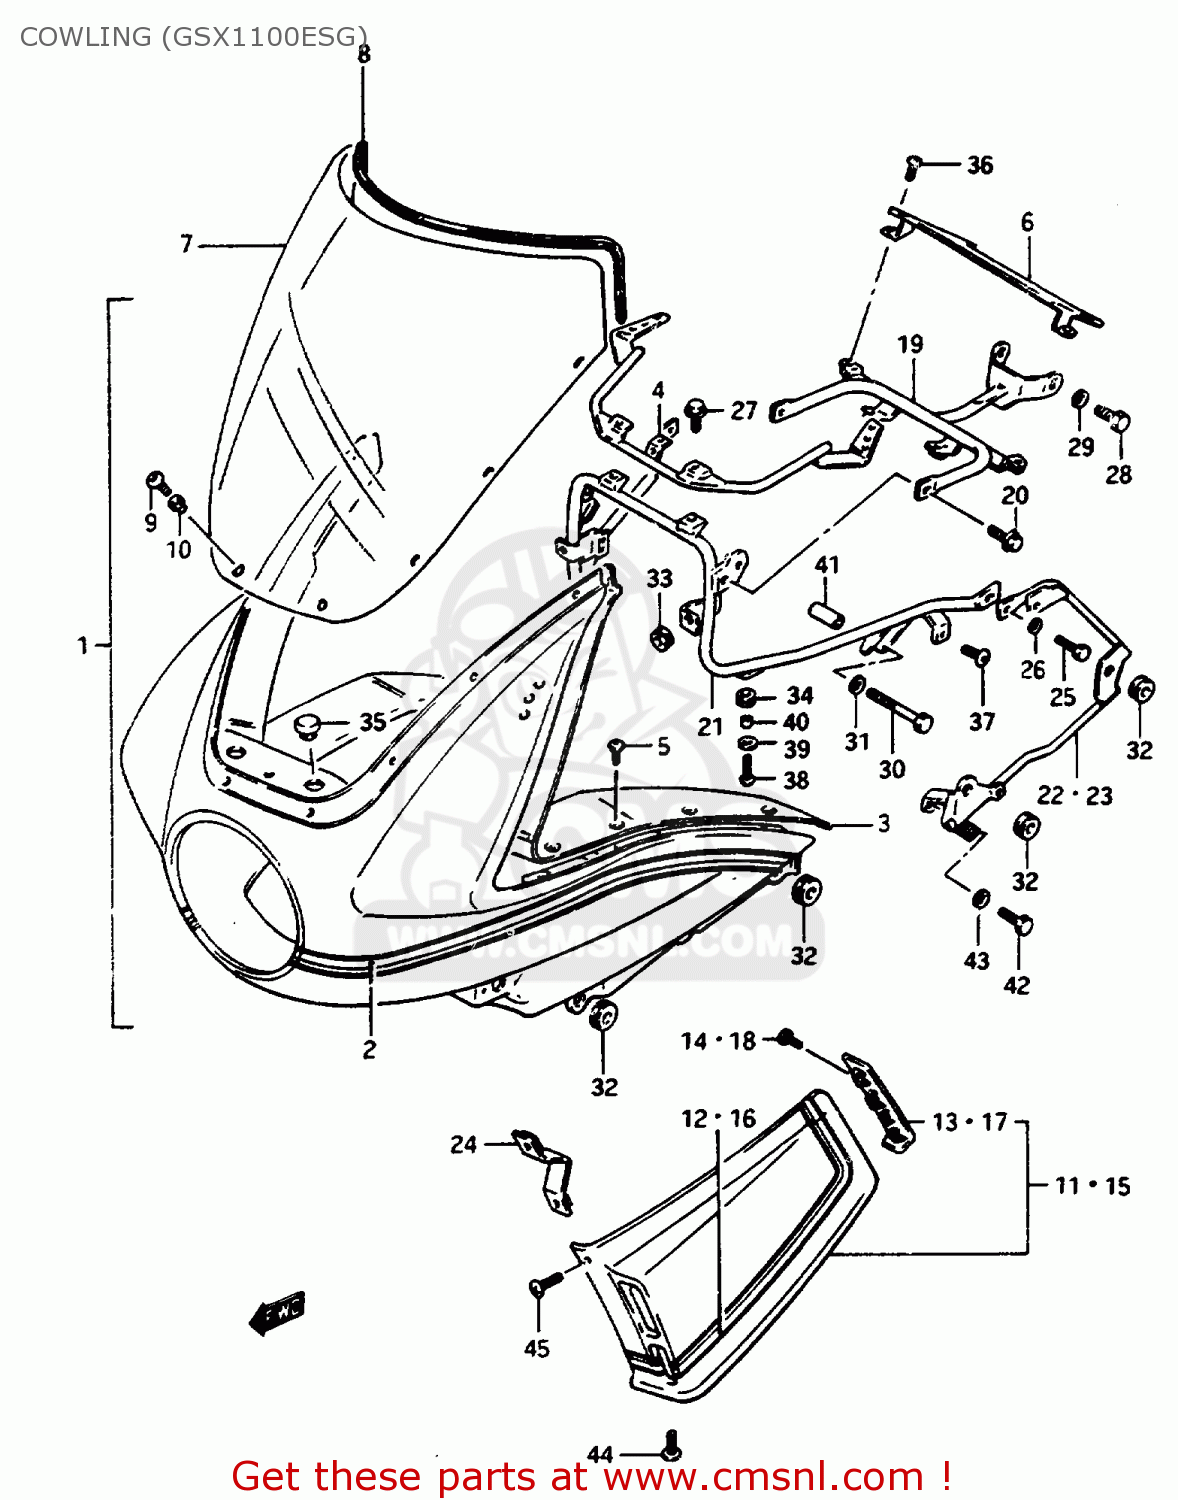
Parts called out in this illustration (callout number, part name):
1	COWLING ASSY (WHITE/RED)
2	TAPE SET,COWLING
3	PANEL,COWLING
4	BRACE,COWLING BODY
5	SCREW, PANEL
6	COVER,METER,REAR
7	SCREEN
8	MOLDING
9	SCREW(5X20)
10	CUSHION
11	COVER, RH (WHITE/RED)
12	TAPE SET,COWLING
13	PANEL,COWL SIDE COVER RR RH
14	SCREW
15	COVER, LH (WHITE/RED)
16	TAPE SET,COWLING SIDE
17	PANEL,COWLING SIDE COVER
18	SCREW
19	BRACE,COWLING,FRONT
20	BOLT
21	BRACE,COWL RR
22	BRACE,COWLING SIDE,RIGHT
23	BRACE,COWLING SIDE,LEFT
24	BRACE,SIDE,FRONT
25	BOLT 6X16
26	WASHER,LOCK
27	BOLT
28	BOLT
29	WASHER,LOCK,8.
30	BOLT
31	WASHER,LOCK,8.
32	CUSHION
33	CUSHION
34	CUSHION
35	PLUG(OD:22)
36	SCREW 5X10
37	SCREW 6X12
38	SCREW, CENTER
39	WASHER(6.5X18X1)
40	SPACER (6.1X9X9)
41	SPACER (8.6X13.8X35)
42	BOLT
43	WASHER,LOCK,8.
44	SCREW
45	SCREW
